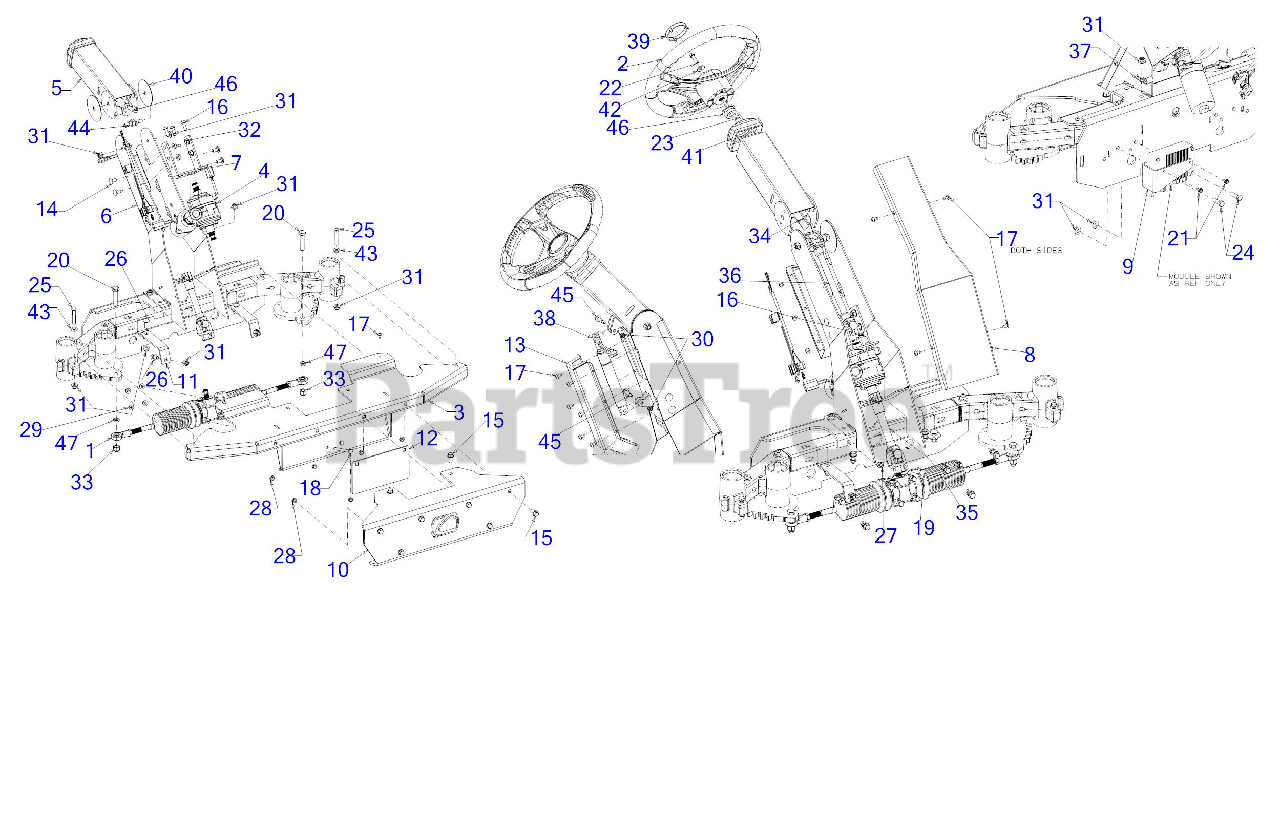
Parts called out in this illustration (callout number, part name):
1	STEERING GEARBOX
2	STEERING WHEEL
14	CARRIAGE BOLT 3/8-16 x .750 GR5
15	SCREW 3/8-16 x .875 GR5
16	SCREW M8-1.25 x 25 GR8.8
17	SCREW 1/4-20 x .5
18	SCREW 5/16-18 x 4.00 GR5
19	SCREW 3/8-16 x 1.50 GR8
20	SCREW 1/2-20 x 2.25
21	SCREW M6-1 x .625
22	SCREW 5/16-18 x 1.00 GR5
23	SCREW #10-16 x 1.25
24	SCREW 3/8-16 x 1.25 GR5
25	SCREW 3/8-16 x 2.0 GR5
26	CARRIAGE BOLT 3/8-16 x 1.00 GR5
27	HEX NUT INS L-3/8-16
28	JAM LOCK NUT
29	FLANGE LOCK NUT 5/16-18
30	FLANGE LOCK NUT
32	HEX LOCK NUT
33	HEX NUT 1/2-20 GR8 NYLON
34	RETAINING RING
35	STEERING SHAFT
36	STEERING SHAFT
37	J TYPE CLIP
38	TILT STEERING DAMPENING CYLINDER
39	STEERING WHEEL CAP
40	COLUMN PLATE
41	STEERING COLUMN COVER
42	BELL WASHER .337 X.867 x .057
43	FLAT WASHER
44	SHOULDER SCREW .498 DIA x .340
45	SHOULDER SCREW
46	FLANGE BEARING
